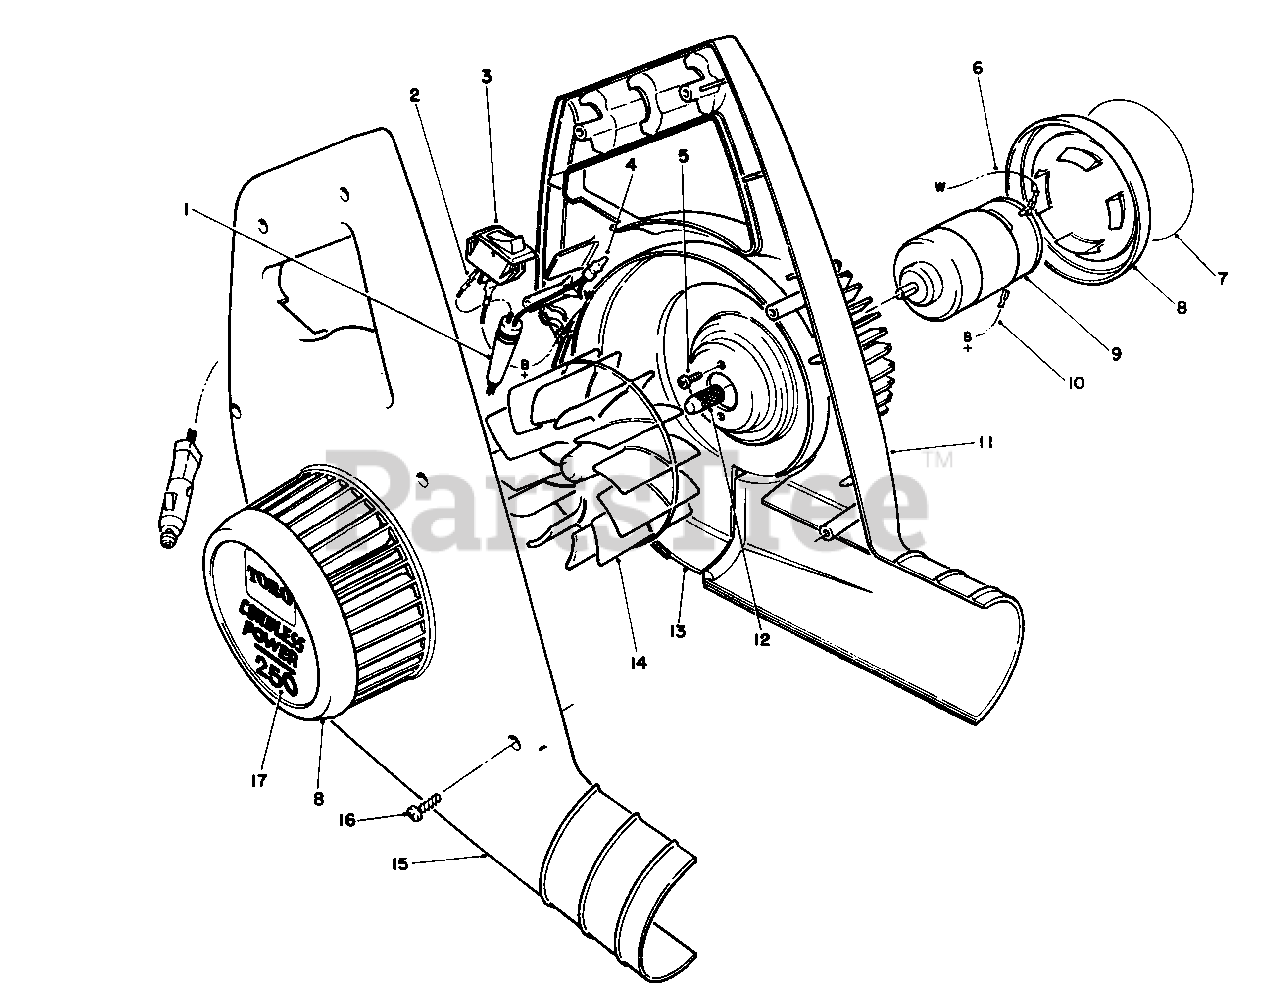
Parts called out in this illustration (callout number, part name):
1	Cord-Power Supply
2	Terminal-Female
4	Connector-Wire
5	Screw-Phillips, Pan Hd.
6	Wire Assembly (White)
7	Decal-Warning
8	Cover-Intake
9	Motor (Incl. Ref. #5, & 12-14)
10	Wire Assembly (Black)
11	Housing-L.H.
12	Shaft-Knurled
13	Cover-Motor
14	Impeller
15	Housing-R.H.
16	Screw-Thread Forming
17	Decal-Toro
